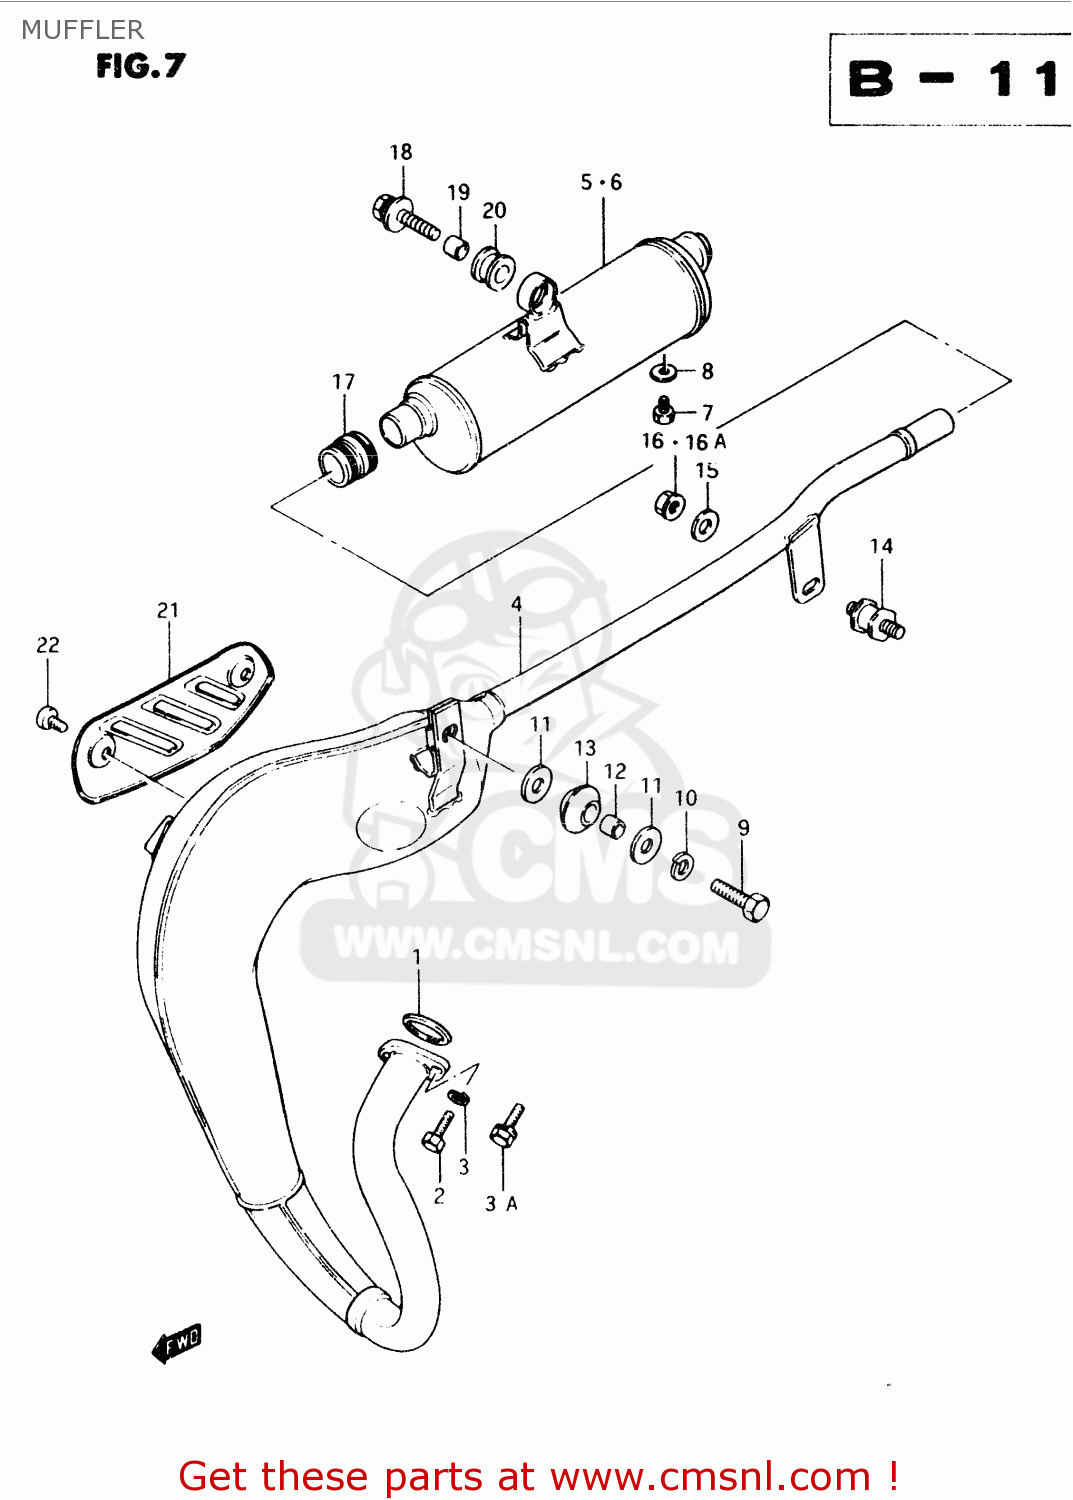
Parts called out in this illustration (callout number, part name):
1	GASKET,EXHAUST PIPE (NAS)
2	BOLT
3	WASHER,LOCK
3A	BOLT
4	MUFFLER, 1ST
5	MUFFLER 2ND
6	MUFFLER ASSY,2ND
7	BOLT 6X8
8	GASKET(6.2X11X1).2 (NAS)
9	BOLT
10	LOCK WASHER
11	WASHER
12	SPACER (8X12X15)
13	DAMPER,MUFFLER,FR
14	BUSH
15	WASHER (8.5X20X1.6)
16	NUT 8MM
16A	NUT
17	CONNECTOR,MUFFLER
18	BOLT 8X35
19	SPACER (8.6X12X17.5)
20	CUSHION
21	COVER,MUFFLER
22	SCREW
